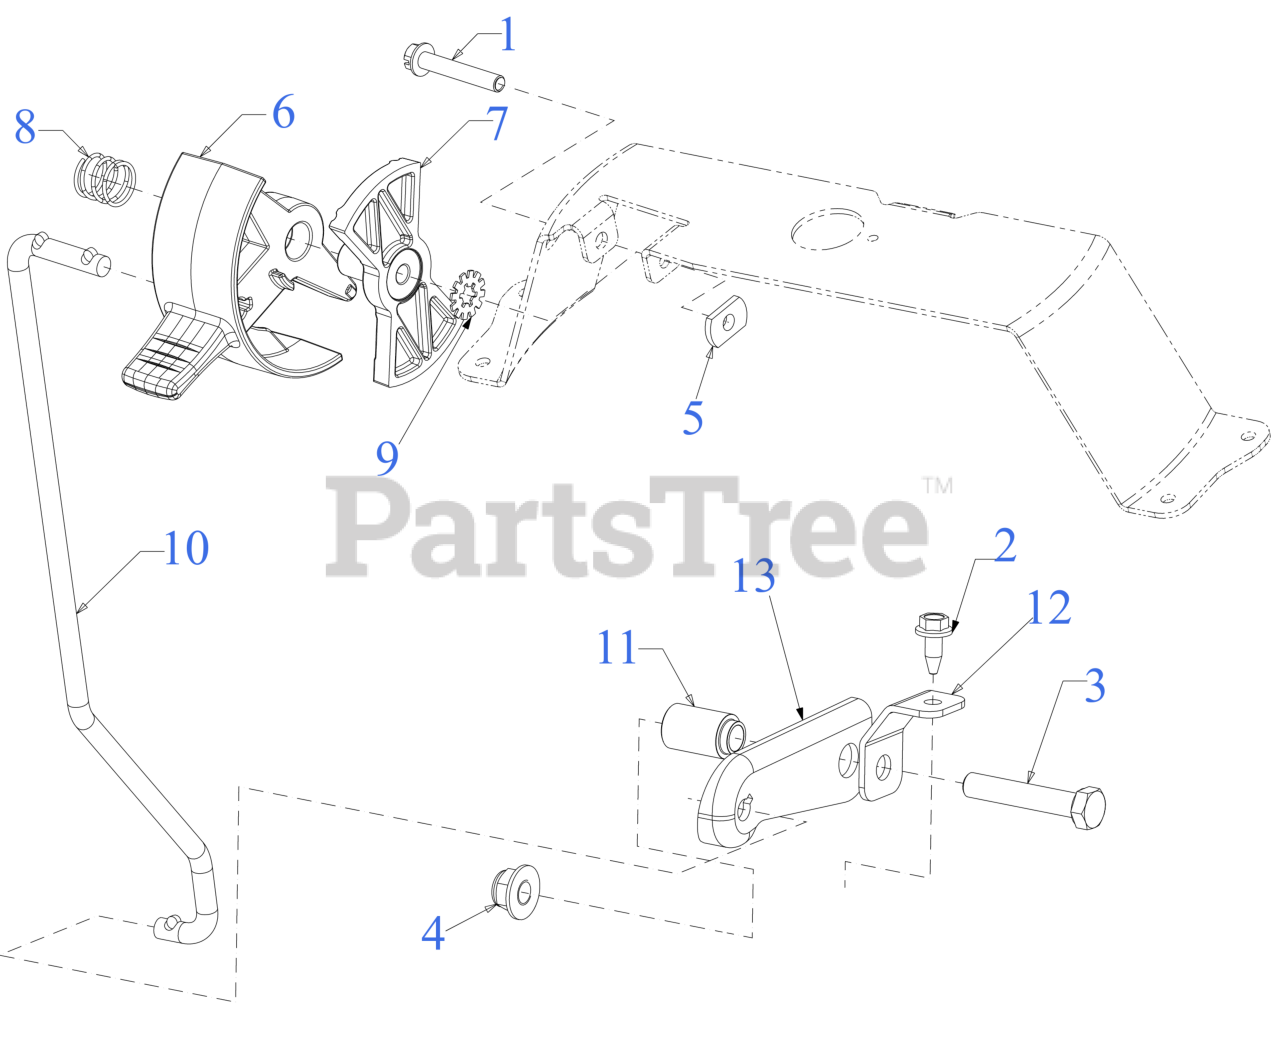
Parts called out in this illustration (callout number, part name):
1	HEX FLANGE BOLT 1/4-20 x 1.5
2	SCREW 3/8-16 x 2.0 GR5
2	SCREW 1/4-20X.625
3	SCREW 3/8-16 x 2 GR5
6	SHIFT LEVER
7	PARK INDEX CONTROL
8	COMPRESSION SPRING
10	SPEED CONTROL ROD
11	FLANGE SPACER
12	SPEED LATCH TAB
13	LATCH SPEED BRACKET
